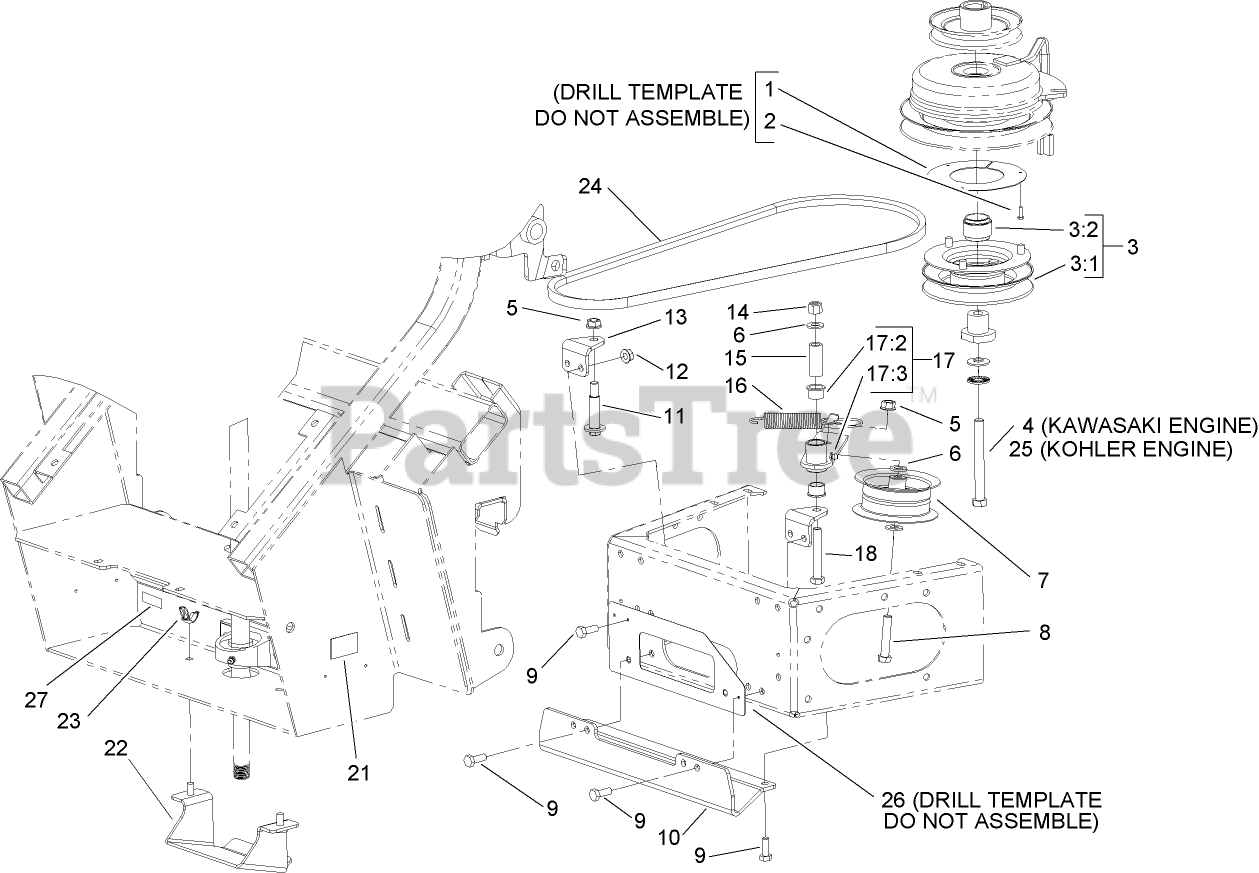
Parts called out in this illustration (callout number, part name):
1	Template-Clutch
2	SCREW-HWH
3	PULLEY ASM
3:1	PULLEY ASSEMBLY
3:2	Spacer-Pulley
4	SCREW-HH
5	NUT-HF
6	WASHER-FLAT
7	PULLEY-IDLER, FLAT
8	SCREW-HH
9	SCREW-HH
11	SCREW-SHOULDER, HWH
12	NUT-HF
13	Bracket-Mount, Idler
14	NUT-LOCK, NI
15	BUSHING
16	Spring-Extension
17	IDLER ARM ASM
17:2	BUSHING
17:3	FITTING-GREASE
18	SCREW-HH
21	Decal-Conversion, Ce
22	Pulley Guard ASM
23	NUT-WING
24	V-BELT
25	SCREW-HH
26	Template-Traction Frame
27	Decal-Grease
